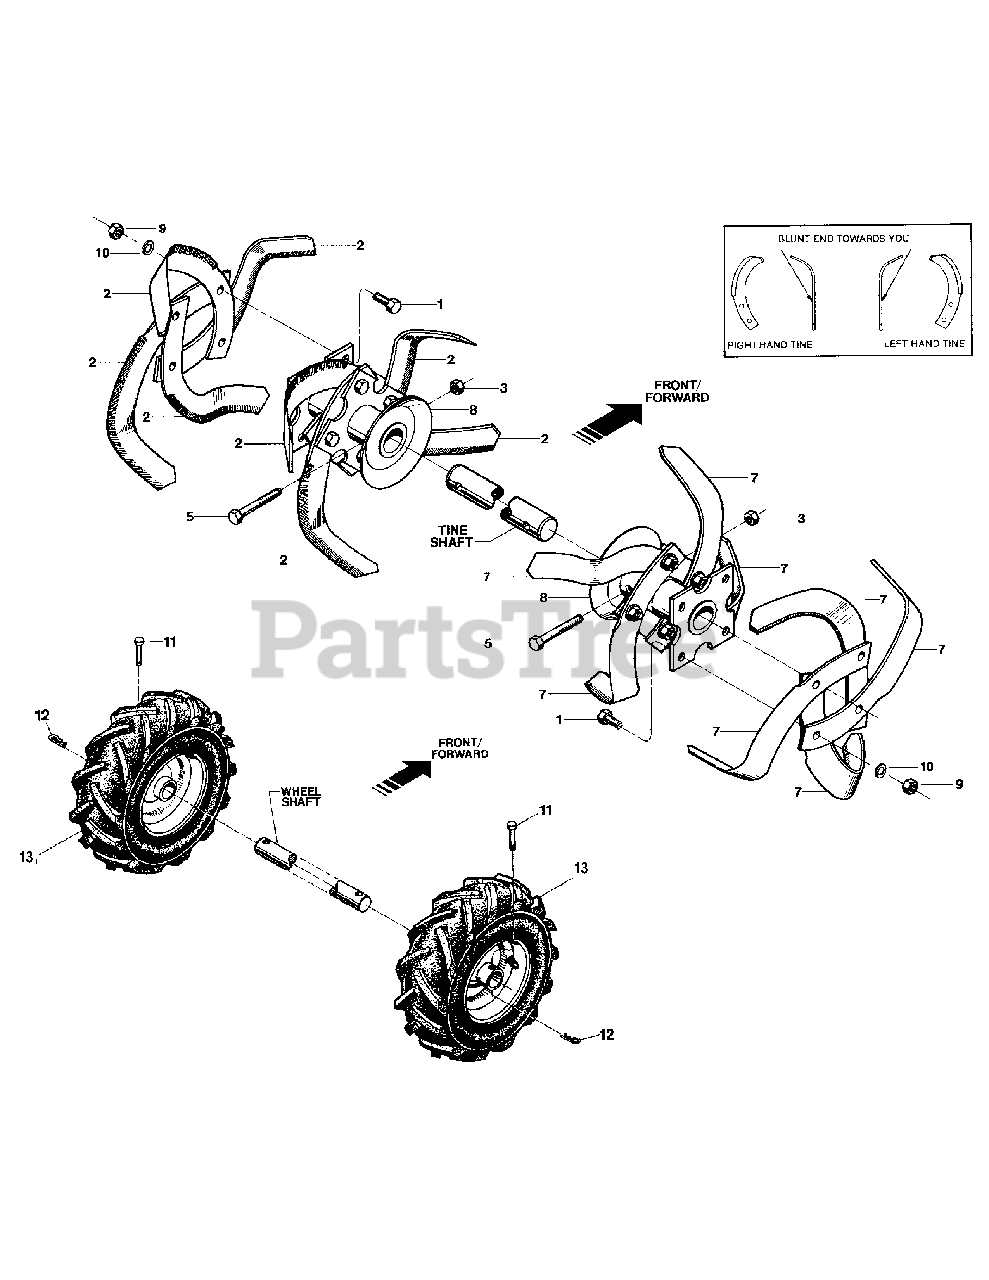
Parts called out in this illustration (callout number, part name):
1	Hex Hd. Screw, 3/8-16 x 1-1/4
2	Bolo Tine-single. Left
3	Hex Locknut, 3/8-16
5	Hex Hd. Screw, 3/8-16 x 2, Grade 8
7	Bolo Tine-single. Right
8	Tine Holder. For left and right sides
9	Hex Nut, 3/8-16
10	Lock Washer, 3/8
11	Clevis Pin, .312 x 1-3/4
12	Hitch Pin
13	Wheel and Tire Assembly
